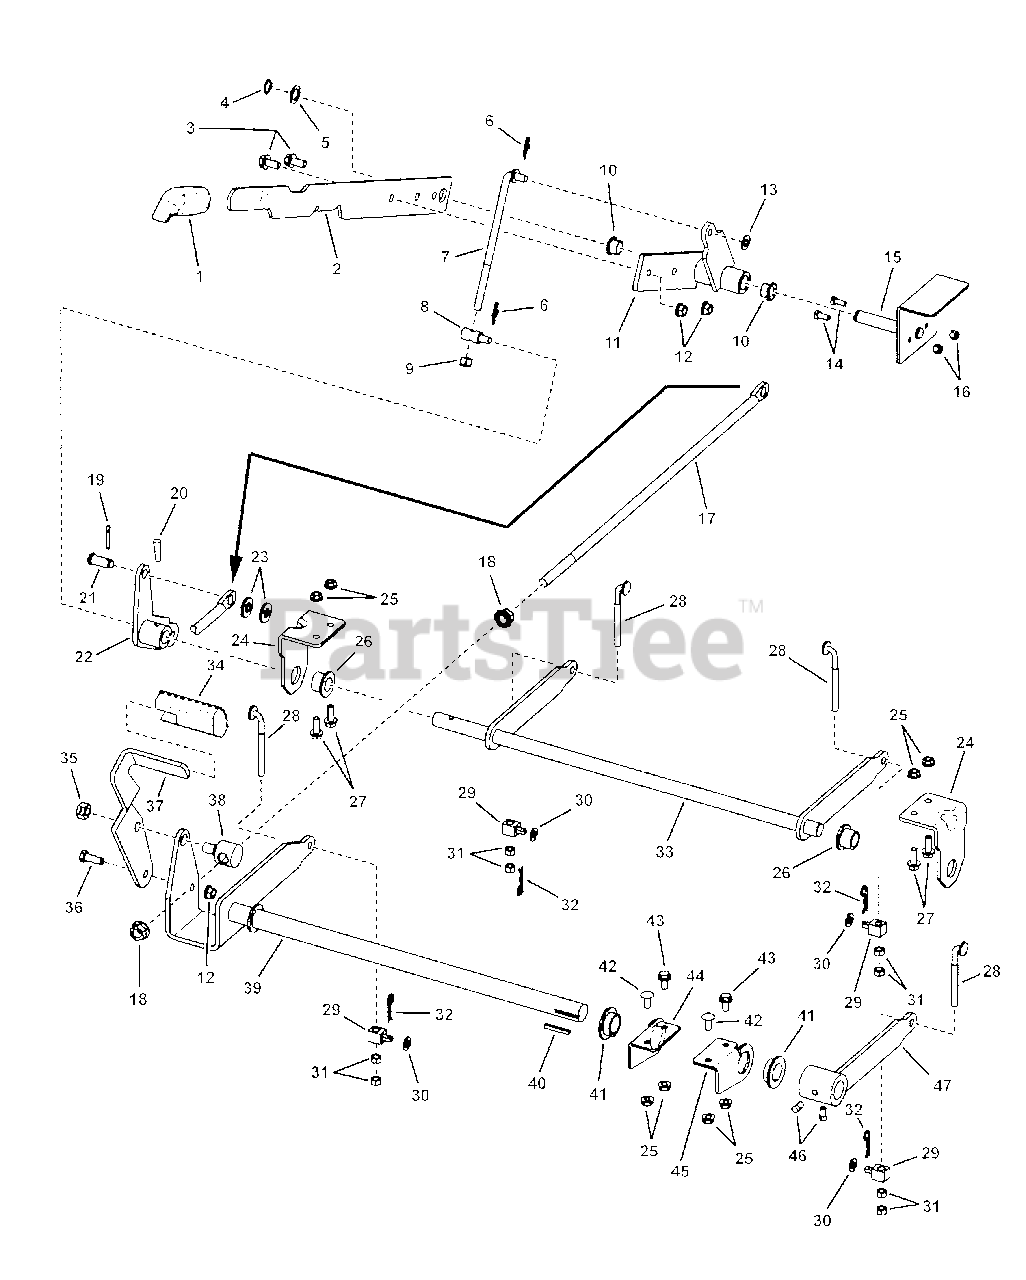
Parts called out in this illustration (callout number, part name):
2	HANDLE, Deck Lift
3	CAPSCREW, Hex Head, Whiz Lock, Flange, 3/8C X3/4 GR5 YZ
4	RETAINING RING, Extension, 5/8
5	WASHER, .64X.99X.05 YZ
6	PIN, Cotter, Self Locking, 3/8, YZ
8	SWIVEL, 3/8 w/Thru Hole Special
9	NUT, Hex Lock Nylon, 3/8F YZ
10	BUSHING, Teflon Impregnated
11	WELD, Handle Lift, Yellow
12	NUT, Hex Flange Lock, 3/8C YZ
13	WASHER, 3/8 SAE YZ
14	CAPSCREW, Hex Head, 1/4C X5/8 GR5 YZ
15	WELD, Handle Support
16	NUT, Hex Lock Nylon, 1/4C YZ
17	ROD, Timing
18	NUT, Hex Flange Lock, 1/2C GR5 YZ
19	PIN, Cotter, 5/32X1 YZ
20	GROOVE PIN, 1/4 X 1-1/4
21	CLEVIS PIN, 1/2X1-1/8 YZ
22	WELD, Link Lift
23	WASHER, .531X1.062X.121 YZ
24	BRACKET, Rear Support, RH
25	NUT, Hex Flange Lock, 5/16C GR5 YZ
26	BEARING, Powdered Metal
27	CAPSCREW, Hex Head, Whiz Lock, Flange, 5/16C X7/8 YZ
28	ROD, Height Adjust, 3.68"
29	SWIVEL, Shift Linkage, Powdered Metal
30	WASHER, .39X.72X.054 BZ
31	NUT, Hex, 5/16C GR5 YZ
32	HAIR PIN, 3/32X1-1/2
33	WELD, Lift Rear, Yellow
34	RUBBER, Foot Pedal
35	NUT, Hex Center Lock, 1/2C GR5 YZ
36	CAPSCREW, Hex Head, 3/8C X1 GR5 YZ
37	BRACKET, Foot ASSIST, Yellow
38	SWIVEL, Timing Rod, Yellow
39	WELD, Bellcrank, RH, Yellow
40	KEY, Square, 3/16X1-1/2
41	BUSHING, Idler, Powdered Metal
42	CARRAIGE BOLT, 5/16C X3/4 GR5 YZ
43	CAPSCREW, Hex Head, Whiz Lock, Flange, 5/16C X5/8 GR5 YZ
44	SUPPORT, Front Deck, RH
45	SUPPORT, Front Deck, LH
46	SHSS, 5/16C X1/2
47	WELD, Front Lift, Yellow
